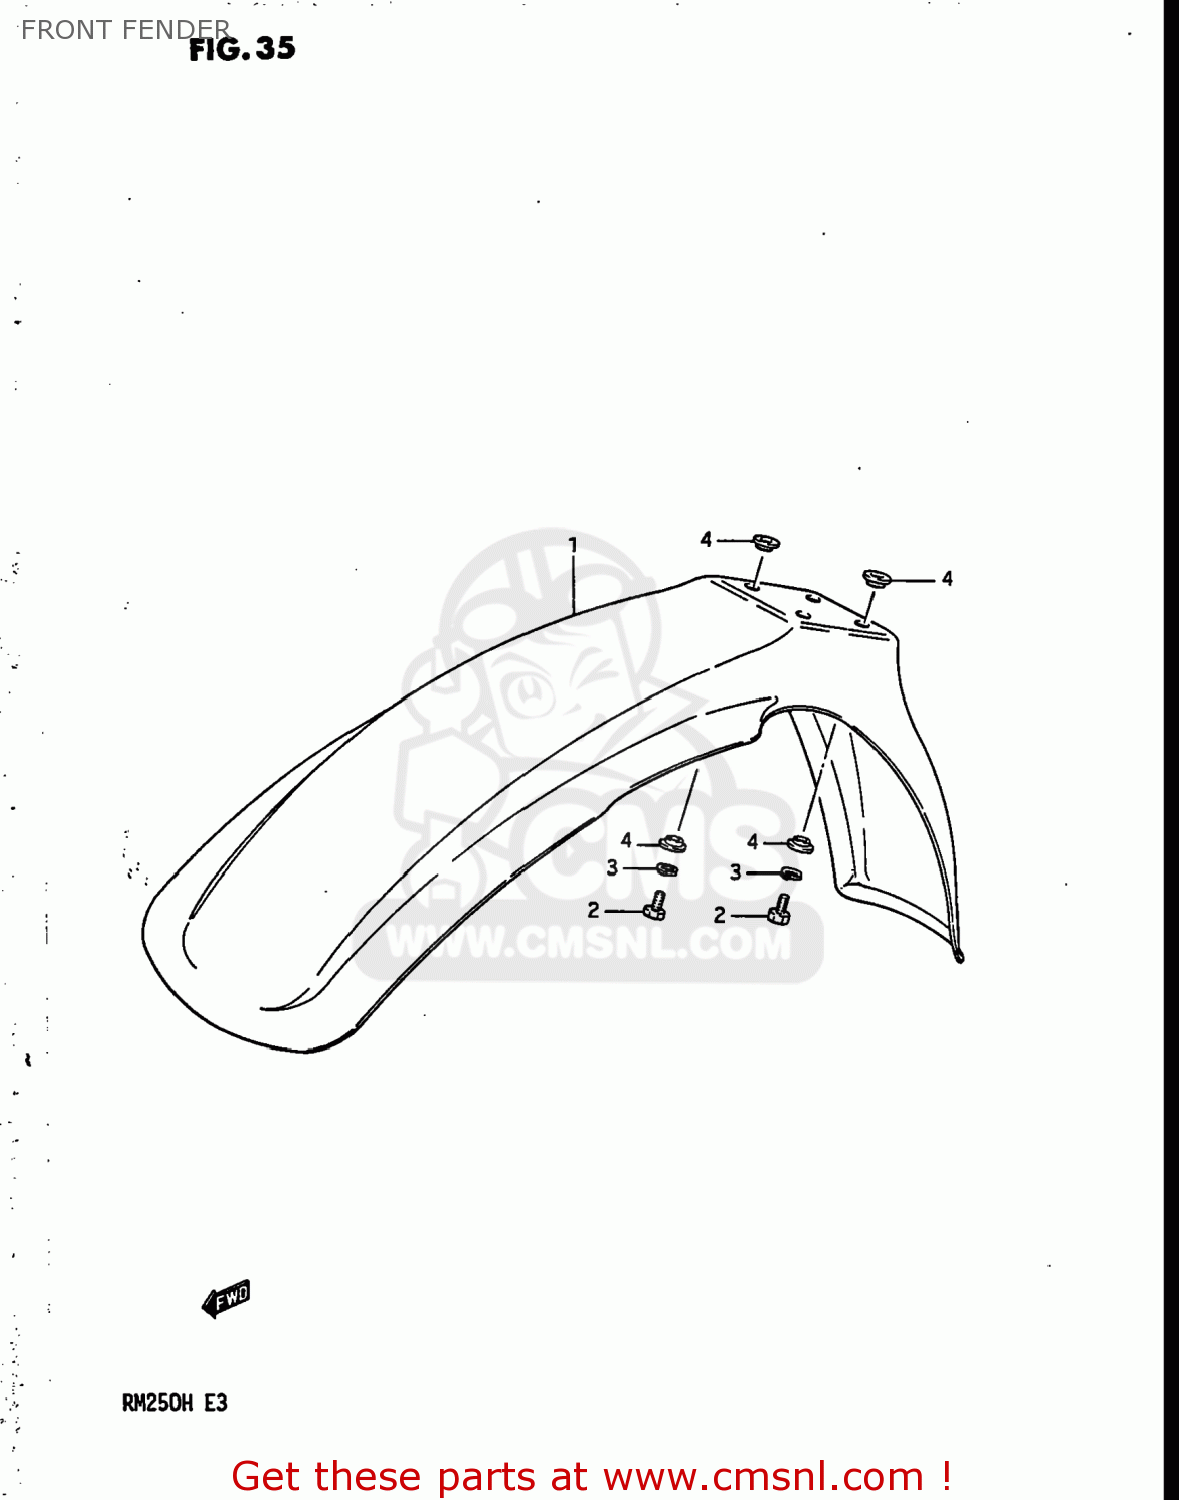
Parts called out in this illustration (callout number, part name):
1	FENDER,FR
2	BOLT
3	WASHER,LOCK
4	WASHER
